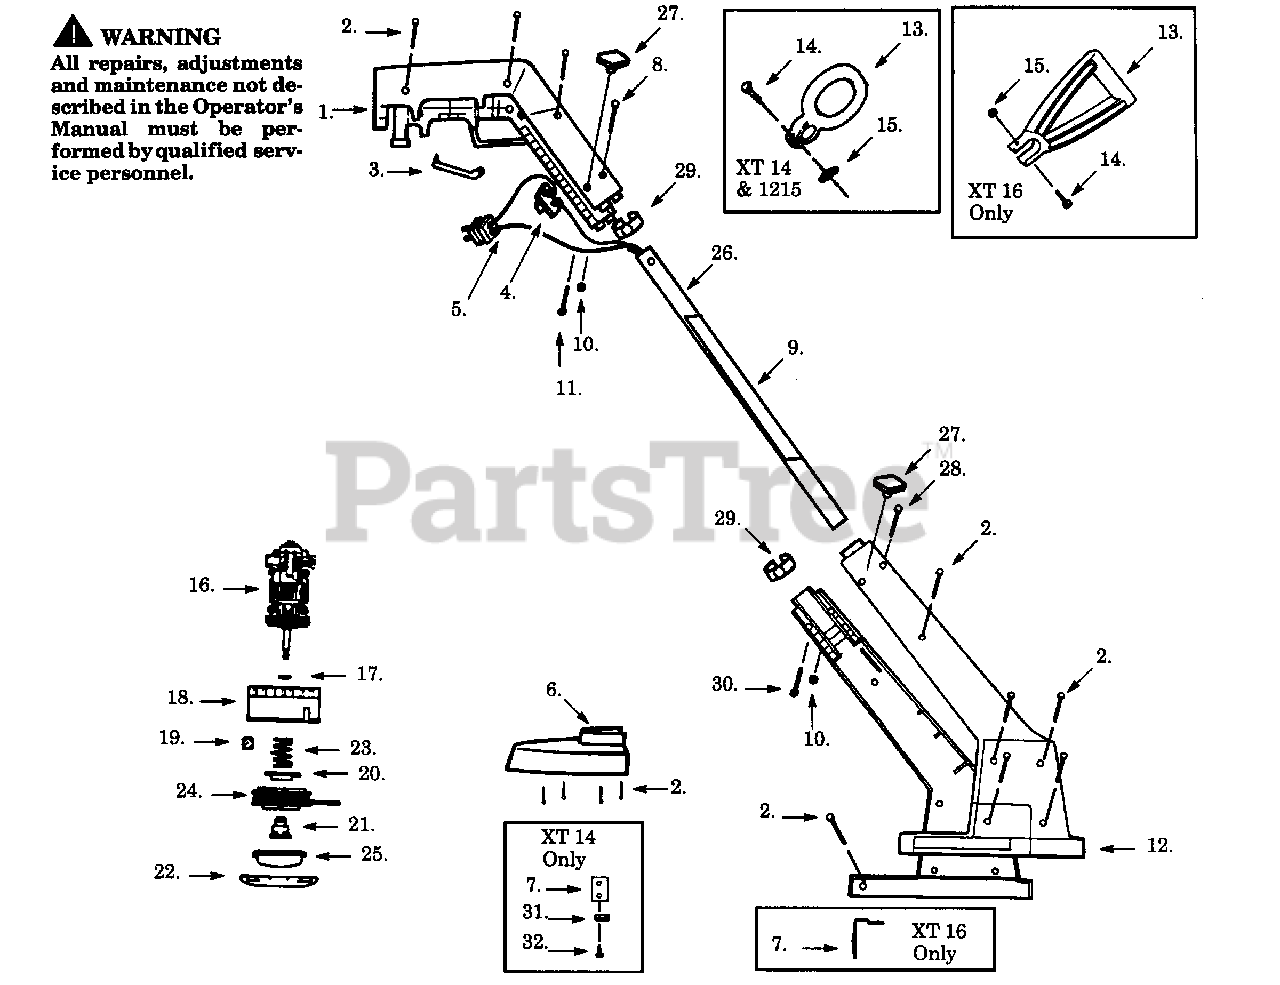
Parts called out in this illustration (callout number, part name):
1	Switch Handle Set, XT14,XT16
1	Switch Handle Set, 1215
4	On/Off Switch
5	Wiring Harness
6	Shield, XT14
6	Shield, XT16
6	Shield, 1215 (w/Line Limiter)
7	Line Limiter, XT14
7	Line Limiter, XT16
8	Screw, Upper
9	Warning Decal
11	Screw, Upper Knob
12	Motor Hsg. Set, XT14
12	Motor Hsg. Set, XT16
12	Motor Hsg. Set, 1215
13	Assist Handle, XT14
13	Assist Handle, XT16
13	Assist Handle, 1215
15	Wing Nut
16	Motor Ass'y., XT14
16	Motor Ass'y., XT16,1215
17	Washer
18	Hub w/ Line Saver
19	Foam Counterweight- XT16 only
20	Spring. Cap
21	Drive Gear Ass'y.
24	Spool w/Line, XT14
24	Spool w/Line, XT16,1215
25	Tap Button
26	Tube Ass'y. w/ Decal, XT14,XT16
26	Tube Ass'y. w/ Decal, 1215
28	Screw, Lower
29	Snap Button
30	Screw, Lower Knob
31	Blade Cover XT14 only
32	Screw XT14 only
